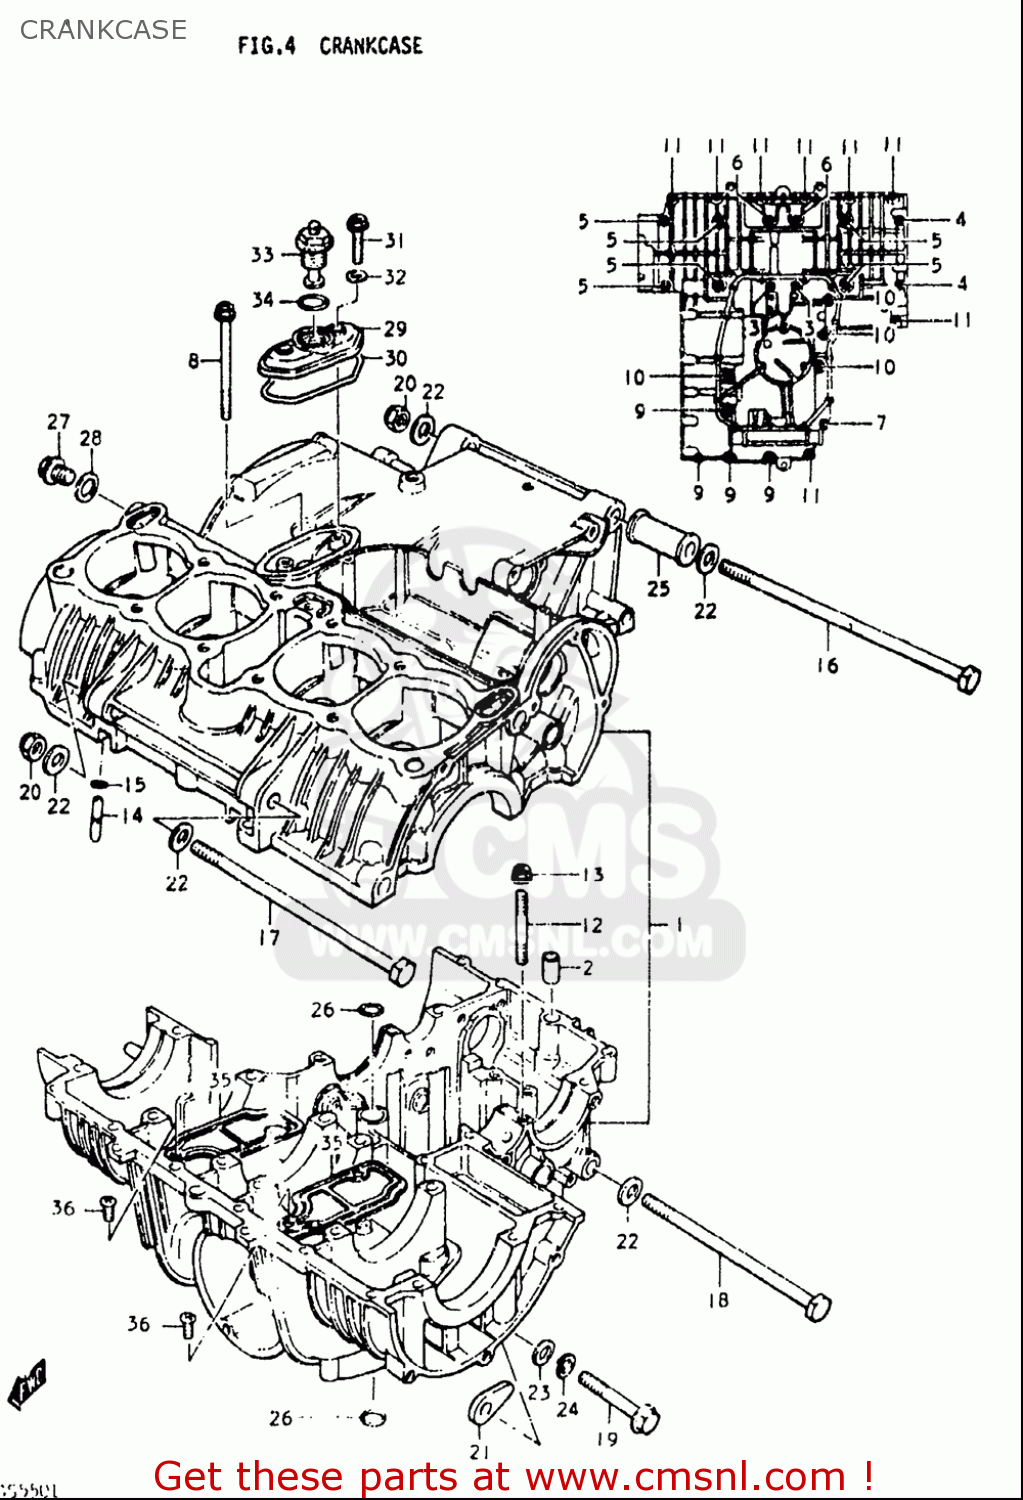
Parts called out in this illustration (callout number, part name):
2	PIN
3	BOLT(8X120)
4	BOLT
5	BOLT
6	BOLT
7	BOLT
8	BOLT
9	BOLT
10	BOLT
11	BOLT
12	STUD BOLT
13	NUT
14	UNION
15	O RING(D:1.05,ID:3.1)
16	BOLT 10X270
17	BOLT(10X200)
18	BOLT(10X165)
19	BOLT
20	NUT
21	NUT
22	WASHER
23	WASHER(10.5X20X3.2)
24	WASHER,LOCK
25	SPACER,ENGINE MOUNT(L:50)
26	O RING(D:3.2,ID:12.9)
27	PLUG(14X12)
28	GASKET(14X19.2X2) (NAS)
29	HOUSING,OIL PRESSURE SWITCH
30	O RING,PRESSURE SWITCH HOUSING
31	BOLT
32	GASKET(5.8X13X1.2) (NAS)
33	SWITCH ASSY,OIL PRESSURE
34	O RING(D:1.9,ID:18.8)
36	SCREW
